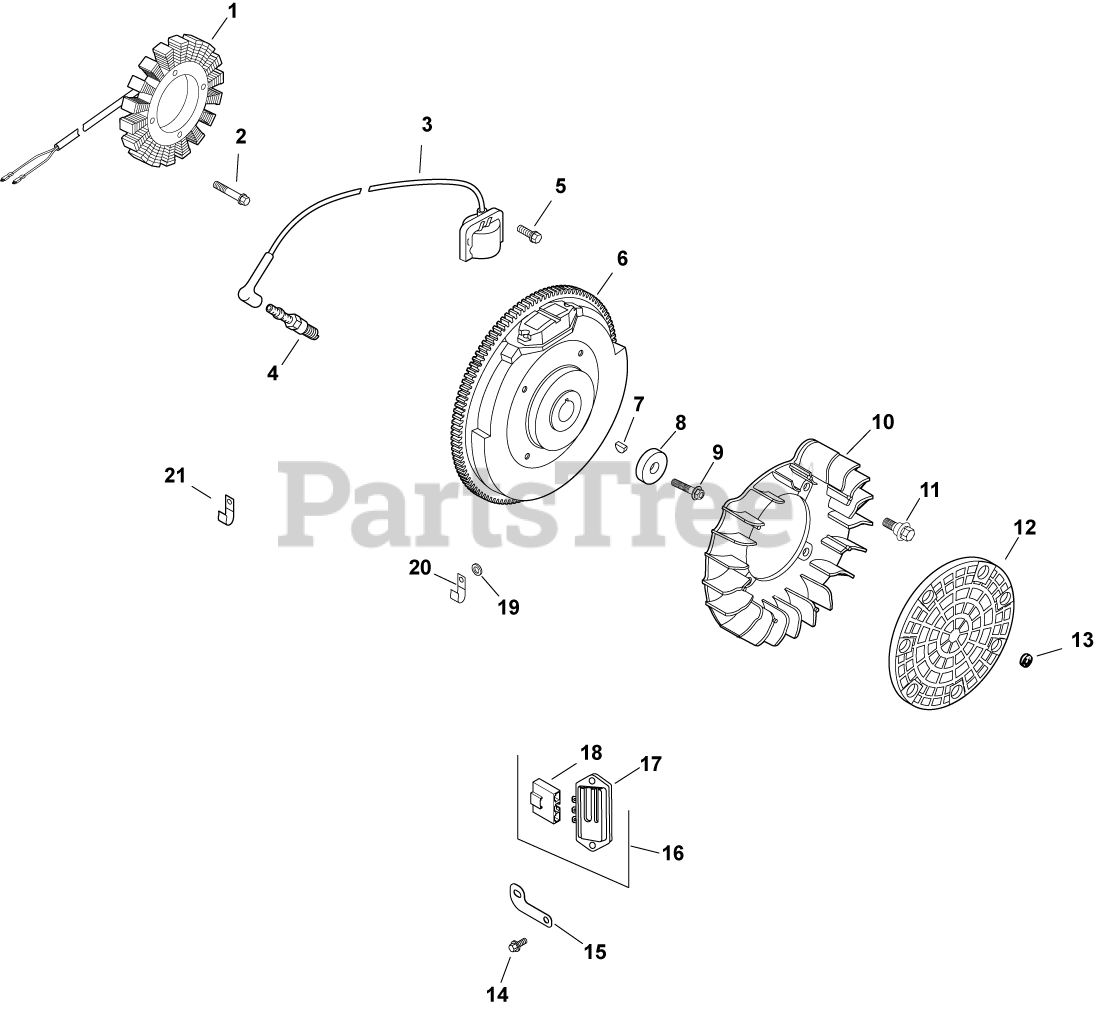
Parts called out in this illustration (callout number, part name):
1	KIT, 25 AMP STATOR ASSY.
2	SCREW, THD FROM M5X0.8X30
3	KIT, MODULE IGNTN (CDI FIXED)
4	PLUG, SPARK (PRO SERIES)
5	SCREW, FLG THD FRM M5X.8X20-(#25086399S)
7	KEY, 3/16" X 5/8"
8	WASHER, FLAT 13/32"
9	SCREW, FLG M10X1.5X45 - (#25086361S)
10	FAN - USE (#24 157 11-S)
11	BOLT, SHOULDER
12	SCREEN, GRASS
14	SCREW, HEX FLANGE HI-LO
15	BRACKET, GROUND STRAP USE 24 518 12-S
16	KIT, FULL WAVE CONVERSION
17	REG/RECTIFIER (20/25 AMP)-USE 25 403 20-
18	CONNECTOR
19	WASHER, FLAT 1/4" (O.D. 1/2")
21	CLIP, CABLE
